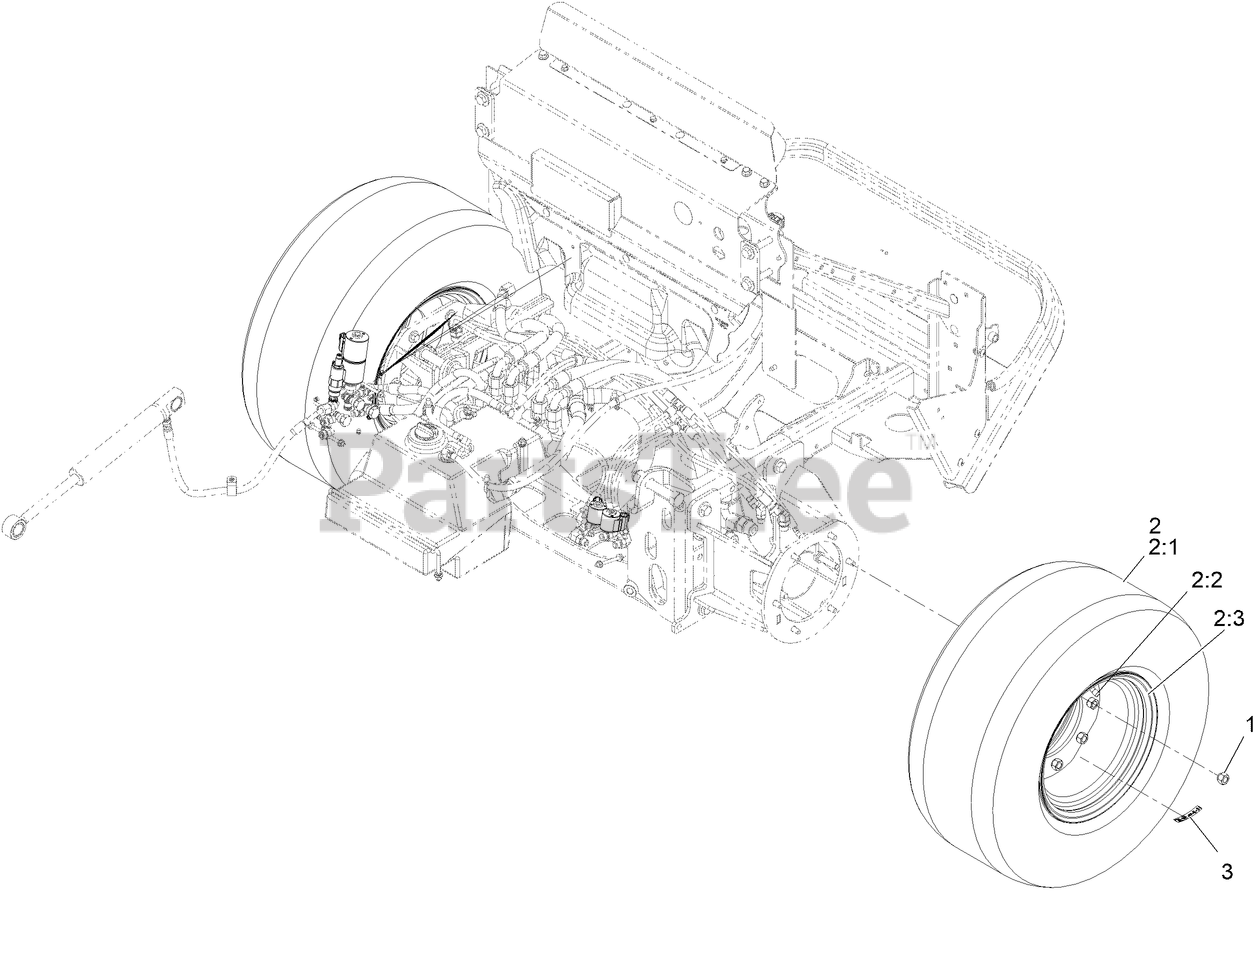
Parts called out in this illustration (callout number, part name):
1	NUT-LUG
2	ASM-TIRE 26X12-12
2:2	Stem-Valve
2:3	WHEEL-12.0X8.5, 8/8.0, WHITE
3	DECAL-WHEEL HUB
